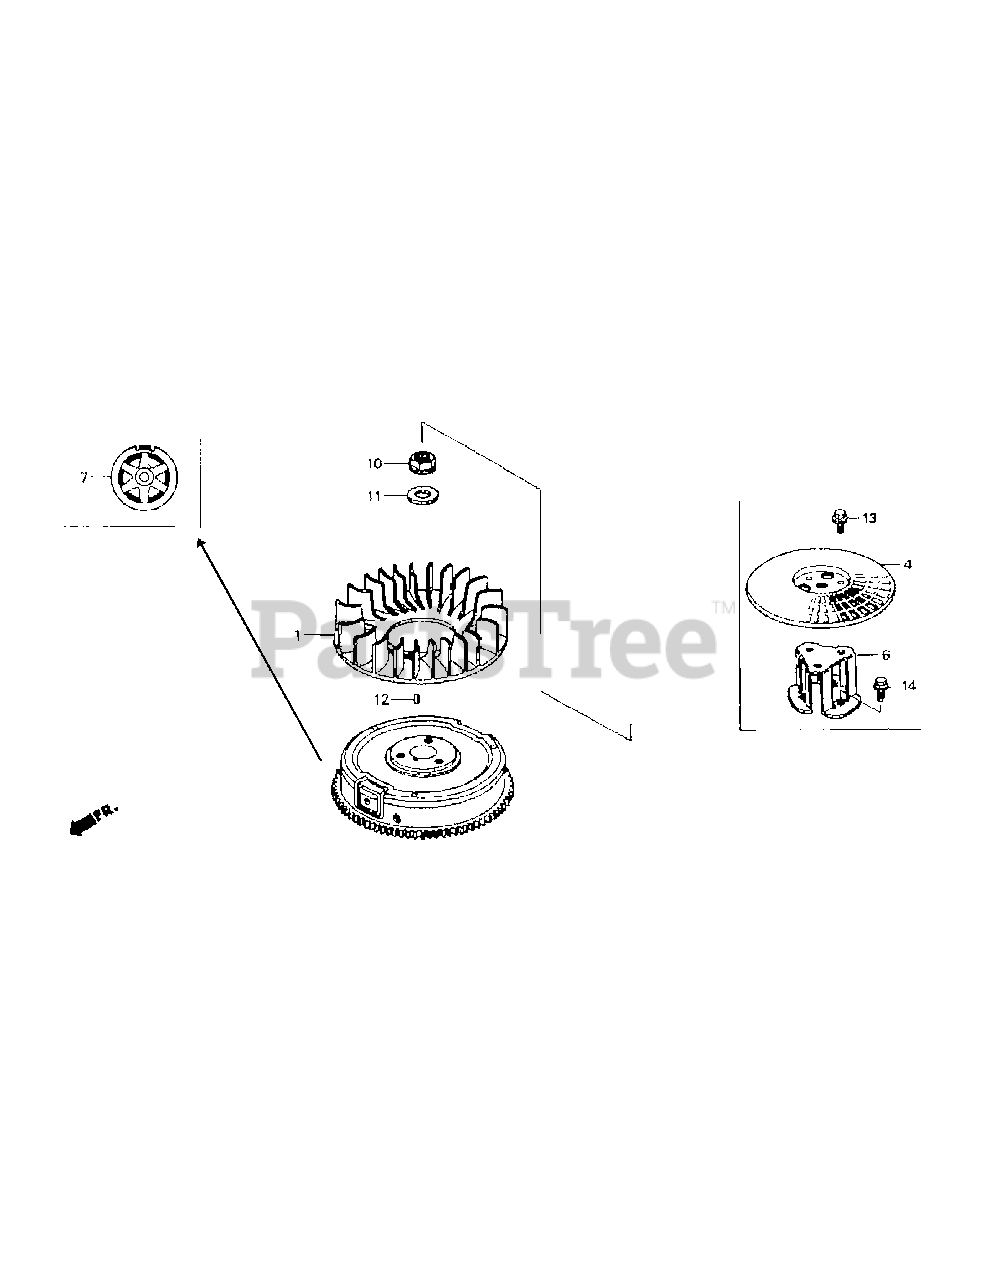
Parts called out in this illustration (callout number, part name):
1	Cooling Fan
4	Screen Grid
6	Screen Grid Holder
10	Flange Nut (20mm)
11	Washer (20mm)
12	Special Woodruff Key (25x18)
13	Flange Bolt (6x12)
14	Flange Bolt (8x16)
